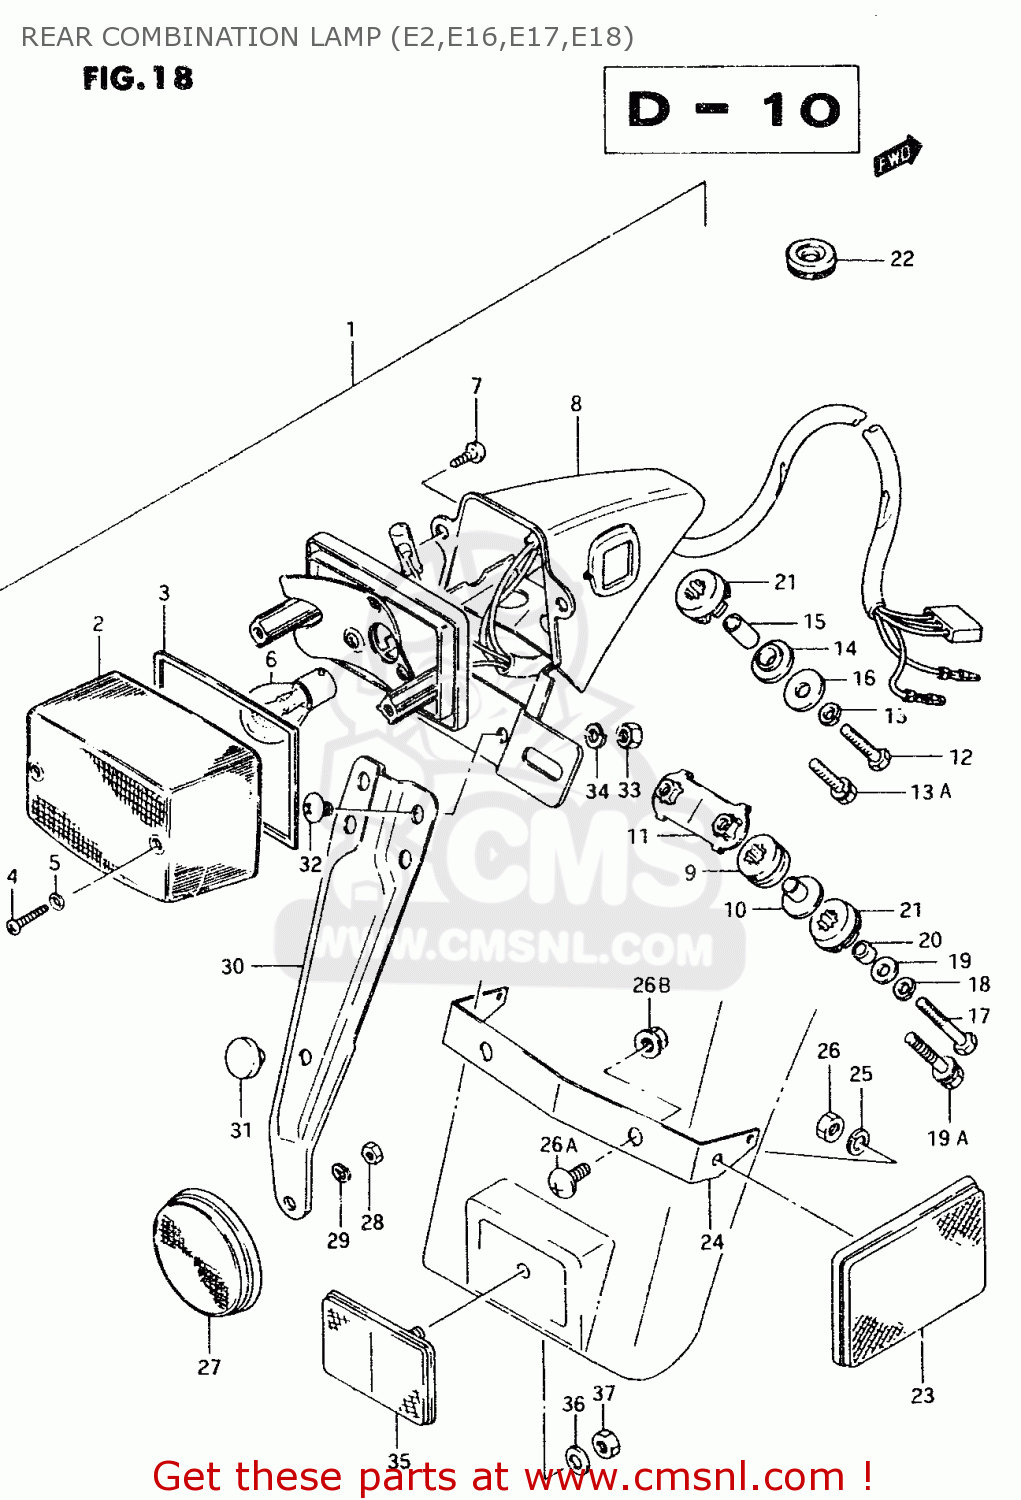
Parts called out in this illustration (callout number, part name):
1	LAMP UNIT,RR COMBNATION
2	LENS
3	GASKET,RR COMBI LAMP LENS (NAS)
4	SCREW
5	GASKET (NAS)
6	BULB(12V21/5W)
7	SCREW
8	BRACKET UNIT,TAIL LAMP
9	CUSHION
10	SPACER
11	PLATE,RR COMBI
12	BOLT
13	WASHER,LOCK
13A	BOLT
14	CUSHION
15	SPACER (6.8X10X16)
16	WASHER (6.5X22X1.6)
17	BOLT
18	WASHER,LOCK
19	WASHER
19A	BOLT
20	SPACER (6.4X9X10.5)
21	CUSHION
22	GROMMET
23	REFLEX REFLECTOR, REAR SIDE
24	BRACKET
25	WASHER,LOCK
26	NUT
26A	SCREW 6X12
26B	NUT
27	REFLEX REFLECTOR,RR
28	NUT
29	LOCK WASHER
30	BRACKET
31	CUSHION
32	SCREW 6X12
33	NUT 6MM
34	WASHER,LOCK
35	REFLEX REFLECTOR,RR
36	WASHER
37	NUT
